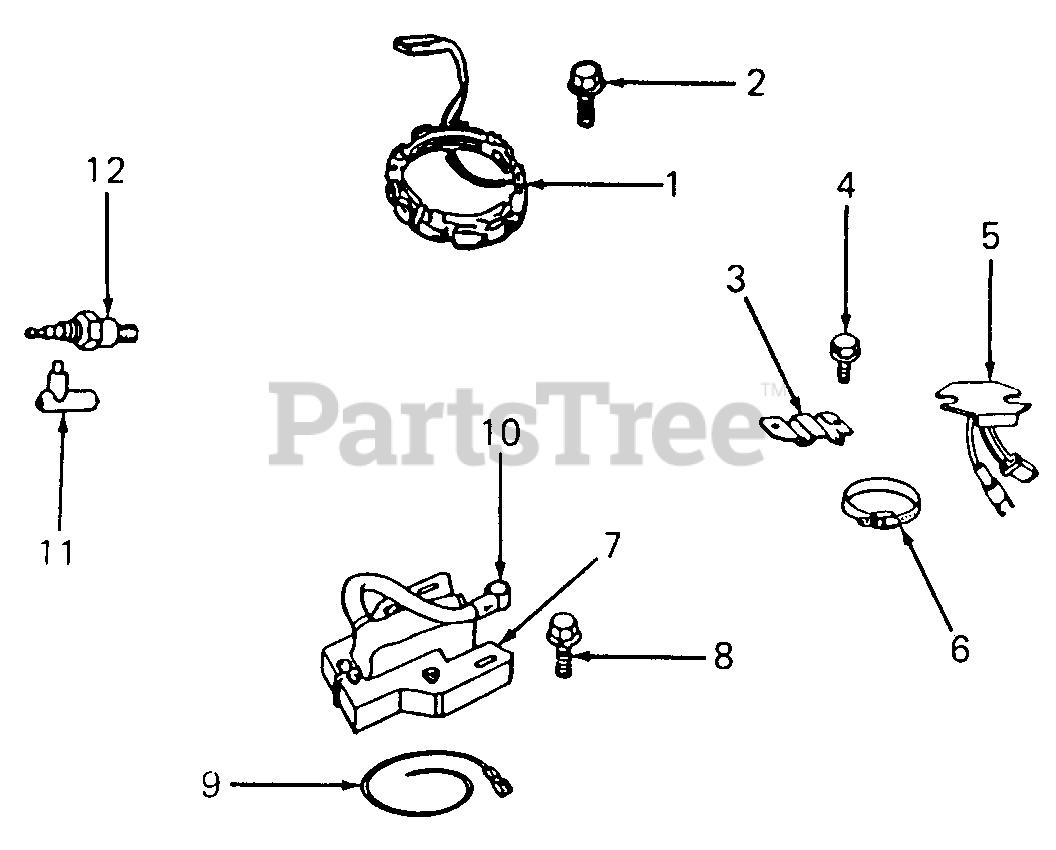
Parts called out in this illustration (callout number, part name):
1	Stator, Alternator
2	Screw, Sem
3	Bracket, Regulator
4	Screw, Regulator
5	Regulator, Alternator
6	Clamp, Regulator
7	Armature, Magneto
8	Screw, Armature Mtg Sem
9	Wire, Ground
10	Terminal, Ignition Cable
11	Elbow, Spark Plug
12	Spark Plug
